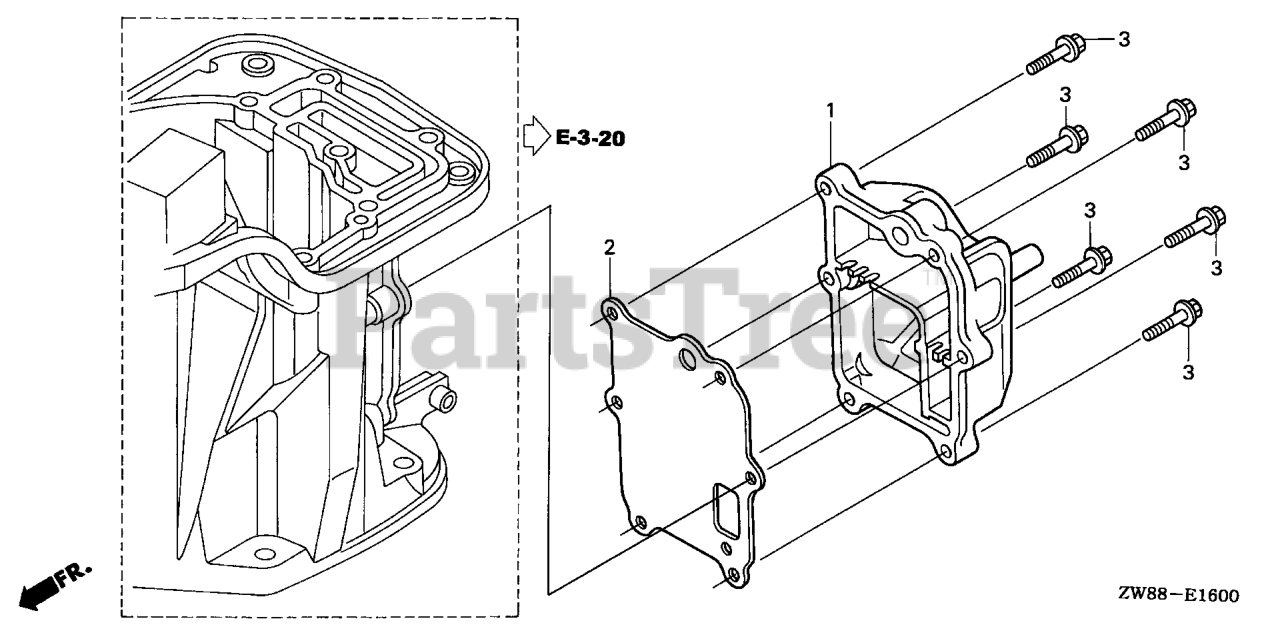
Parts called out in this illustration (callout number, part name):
1	COVER, EX. CHAMBER
2	GASKET, EX. CHAMBER
3	BOLT, FLANGE (6X23) Use from Frame SN 4800343.
